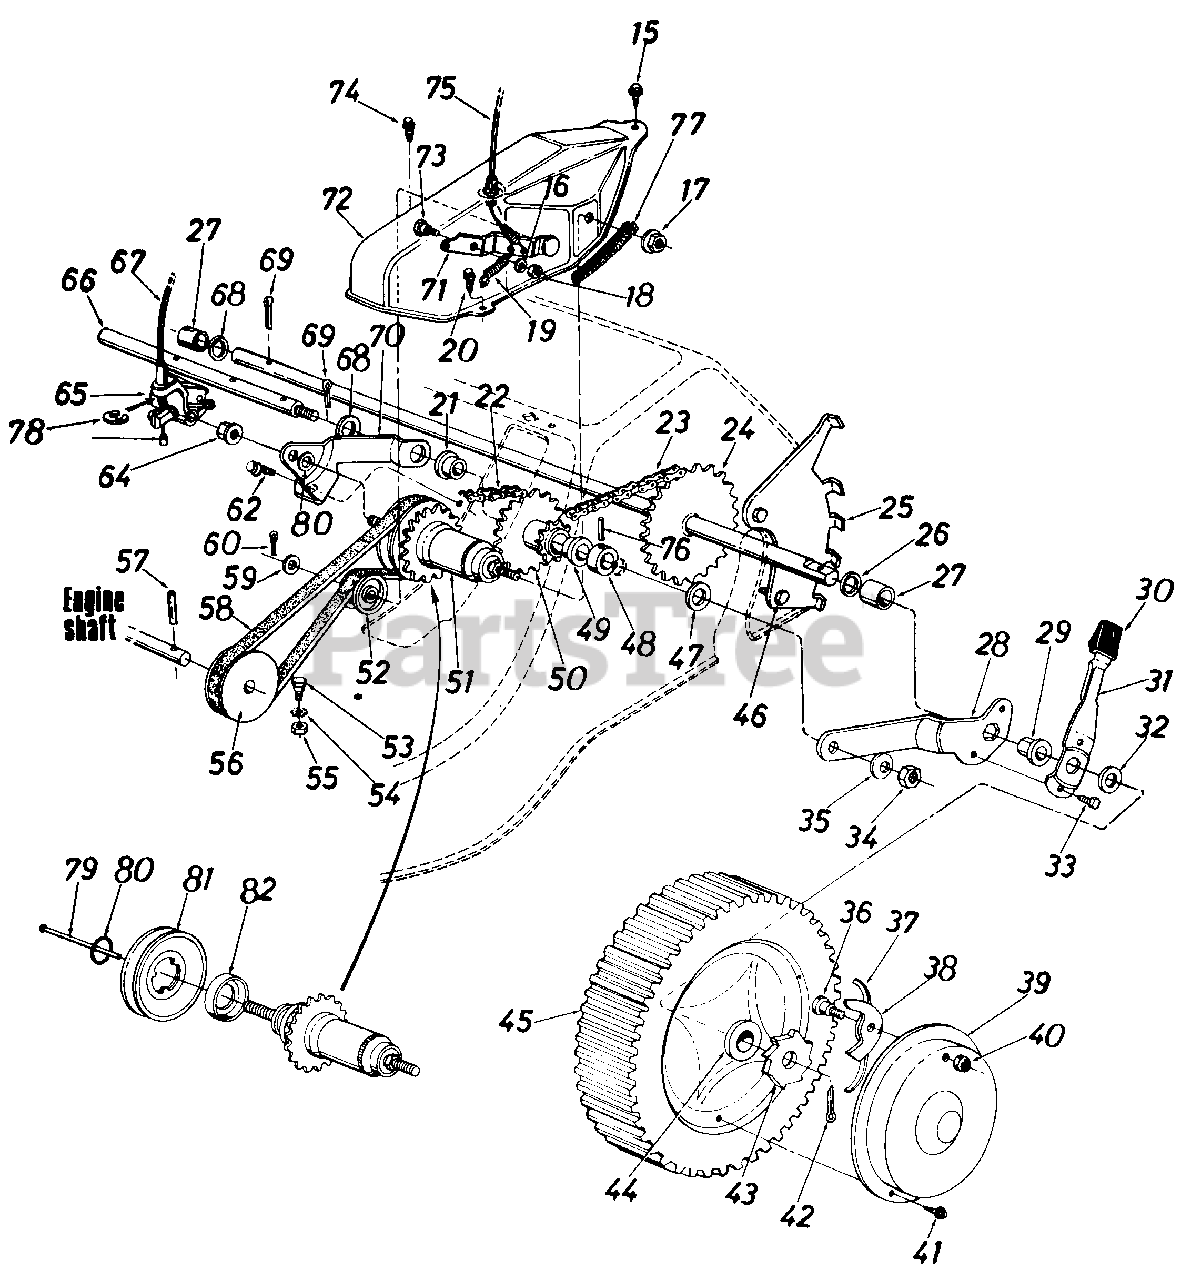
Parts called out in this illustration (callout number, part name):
15	Hex Drilling Scr. #10 x .50" Lg.
16	L-Wash. 1/4" I.D.
17	Hex Nut 3/8-24 Thd.
18	Hex Nut 1/4-20 Thd.
19	Extension Spring .33" O.D. x 1.12" Lg.
20	Hex Wash. S-Tap Scr. 1/4-20 x .50" Lg.
21	Flg. Brg. .506" I.D.-Plastic
22	#48 Chain 1/2" Pitch x 38 Links
23	#48 Chain 1/2" Pitch x 32 Links
24	Rear Shaft Ass'y. 20.75" Lg.
25	Index Plate Rear-L.H.
26	Fl-Wash. .510" I.D. x 1.0" O.D.
27	Spacer.740" I.D. x .83" O.D.
28	Pivot Brkt.-L.H.
29	Hex Flange Brg. .506" I.D.-Plastic
30	Spring Lever Knob
31	Spring Lever
32	Fl-Wash. .531" I.D. x .930" O.D.
33	Hex B-Tap Scr. 1/4 x .38"
34	Hex iam Nut 3/18-16 Thd.
35	Bell-Wash. .400" I.D. x .88" O.D.
36	Shld. Bolt .342" Dia. x .268
37	Spring-Nylon
38	Pawl
39	Hub Cap
40	Hex Ins. L-Nut 1/4-20 Thd.
41	Pan Hd. Tap Scr. #12 x .50" Lg.
42	Cotter Pin 118" Dia. x 1.00" Lg.
43	Ratchet Wheel 1.62" O.D.
44	Fl-Ball Brg. 1/2" I.D.
45	Wheel Ass'y. Comp. 8x 1 .75
46	Hex L-Wash. Hd. AB-Tap Scr. 1/4 x.62" Lg.
47	Bell-Wash. .400" I.D. x 1.13" O.D.
48	Spacer. 505" I.D. x .88" O.D.
49	Flg. Brg. .506" I.D. Plastic
50	9 and 21 Tooth Sprocket Ass'y.
51	Shimano 3-Sp. Hub w/18 Tooth Sprocket
52	Fl-Idler Plastic 1.62" Dia.
53	Shld. Bolt .437" Dia. x .180
54	L-Wash. 5/16" I.D.
55	Hex Nut 5/16-18 Thd.
56	1/2" "V"-Engine Pulley .50" I.D. x 2.80" O.D.
57	Spring Pin Spir. 3/16" Dia. x 1.50" Lg.
58	"V"-Belt 1/2" x 26.0" Lg.
59	Fl-Wash. .531" I.D. x .930" O.D.
60	Cotter Pin 1/18" Dia. x 1.00" Lg.*
62	Hex Wash. Hd. Tap Scr. 5/16-18 x .75" Lg.
64	Hex Nut 3/8-24 Thd.
65	Shimano 3-Sp. Shift Bell Crank
66	Pulley Shaft 10" Lg.
67	Shimano 3-Sp. Solid Shift Cable
68	Fl-Wash. .531" I.D. x .930" O.D.
69	Cotter Pin 3132" Dia. x 1.00" Lg .
70	3-Sp. Hub Bracket
71	Idler Bracket Ass'y.
72	3-Sp. Belt Cover
73	Shld. Bolt .375" Dia. x .181
74	Hex TT-Tap Scr. 1/4-20 x .75" Lg.
75	S.P. Cable-53" Lg.-Blue
76	Spring Pin Spir. 3116" Dia. x 1.0" Lg.
77	Trim Strip
78	Snap Ring
79	Shifting Pin
80	Pulley Snap Ring
81	1/2" V-Pulley 1.375" I.D. x 3.25" O.D.
82	Shimano 3-Sp. Dust Cover
